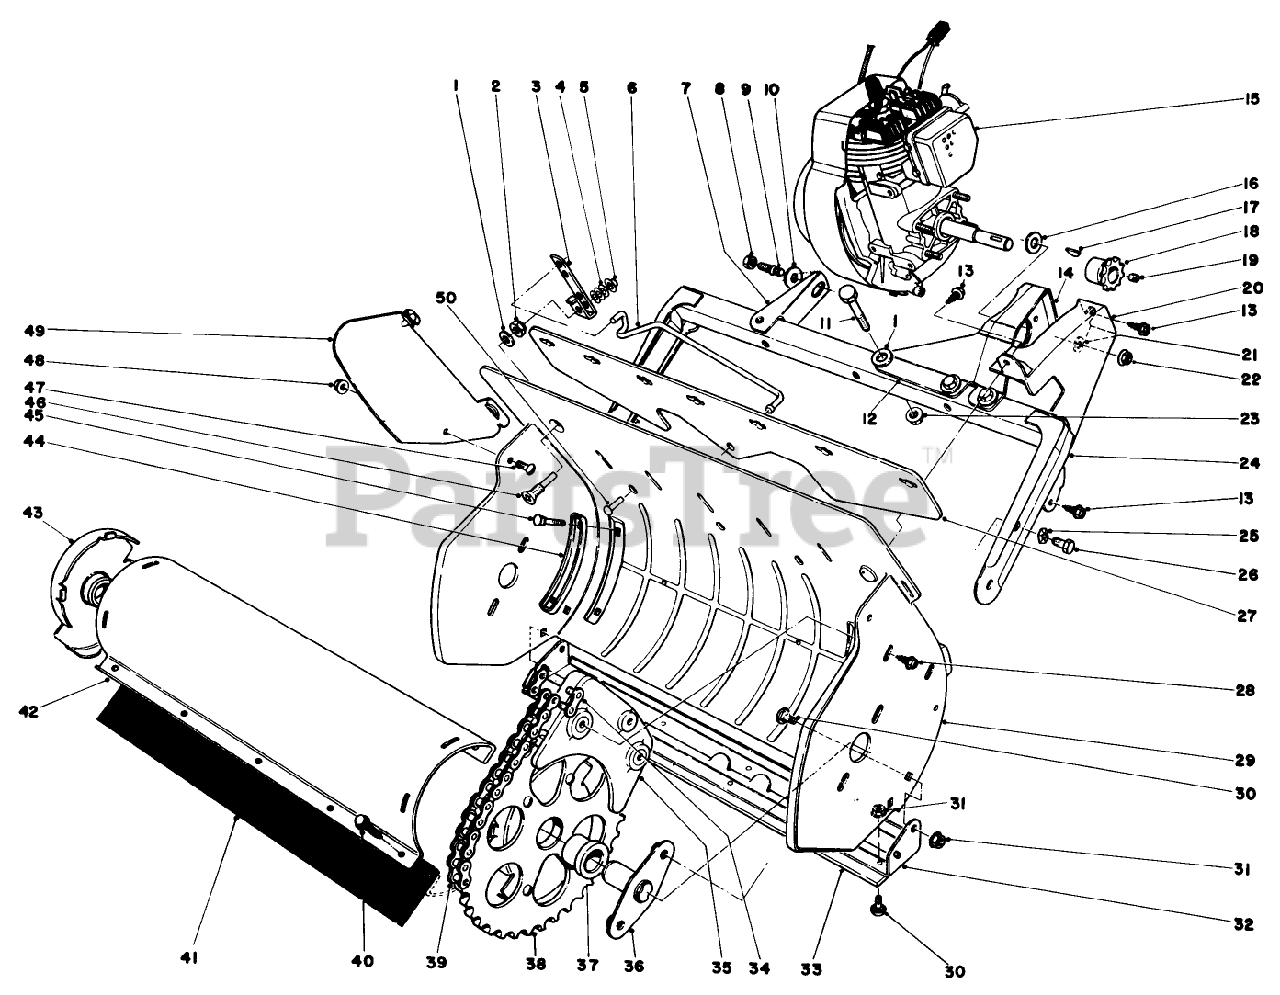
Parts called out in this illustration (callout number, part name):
1	WASHER-FLAT
2	Locknut
4	WASHER-FLAT
5	NUT-SPEED
11	SCREW-HH
13	SCREW-HWHTF
15	Engine
16	WASHER-FLAT
17	KEY-WOODRUFF
19	SCREW-HSH
22	NUT-HF
23	NUT-LOCK, HHF
26	SCREW-HH
28	SCREW-HWHTF
30	SCREW-CARR
31	NUT-KEPS
33	SCRAPER
34	LINK-CONNECTING, NO. 35
37	ROTOR BUSHING
38	End Cap Assembly L.H. (Incl. Ref. #37)
39	ROLLER CHAIN
41	ROTOR BLADE
45	Bolt-Carriage
47	SCREW-PTH
48	NUT-LOCK, FLANGE
